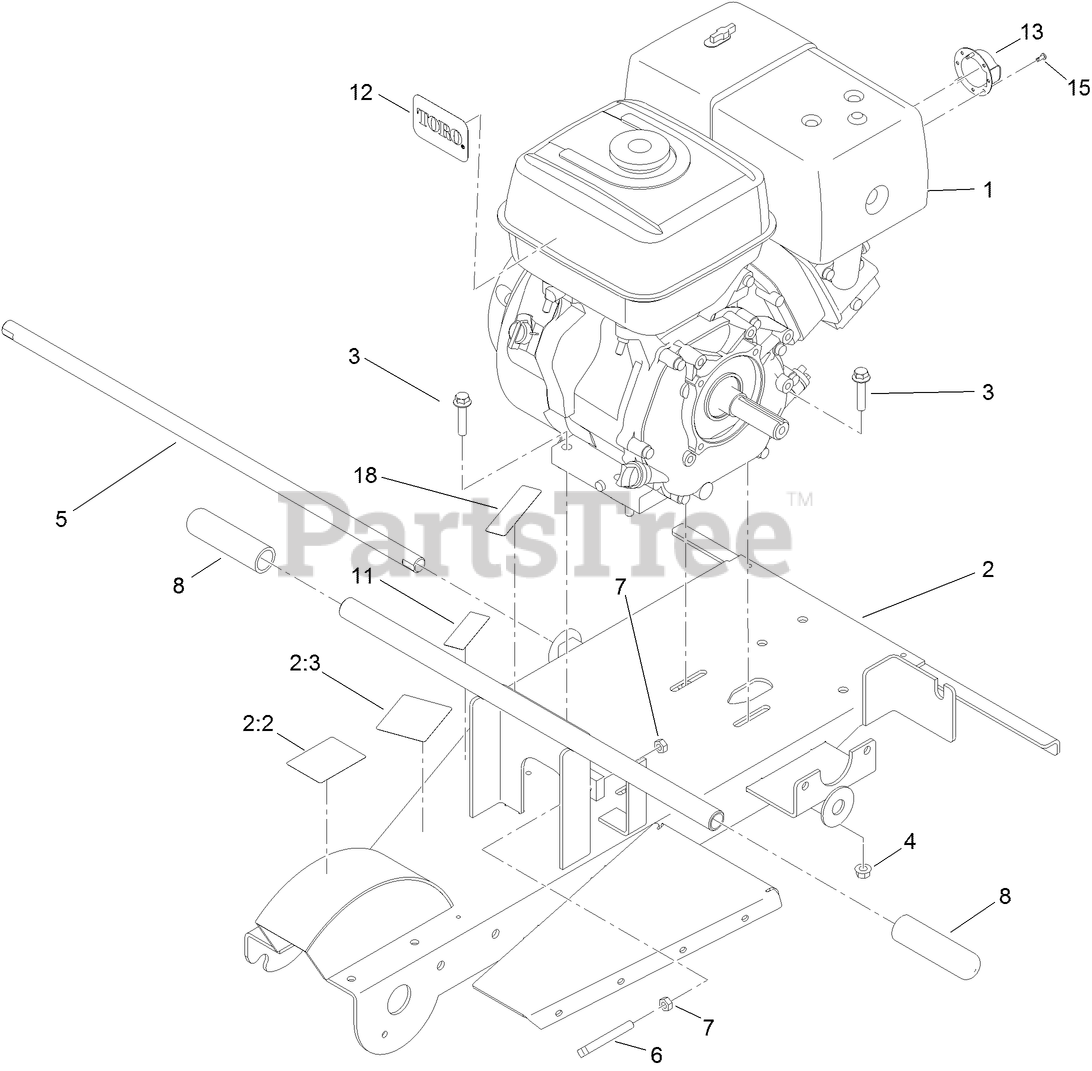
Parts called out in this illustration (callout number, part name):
2	FRAME ASM
2:2	DECAL-DANGER
2:3	DECAL-CAUTION
3	SCREW-HHF
4	NUT-HF
5	BAR-AXLE
6	SCREW-SET, SQH
7	NUT-HEX
8	GRIP-HANDLE
11	DECAL-REGULATORY
12	DECAL
13	DEFLECTOR-EXHAUST
15	SCREW-TAP
18	DECAL-ARRESTER, SPARK
